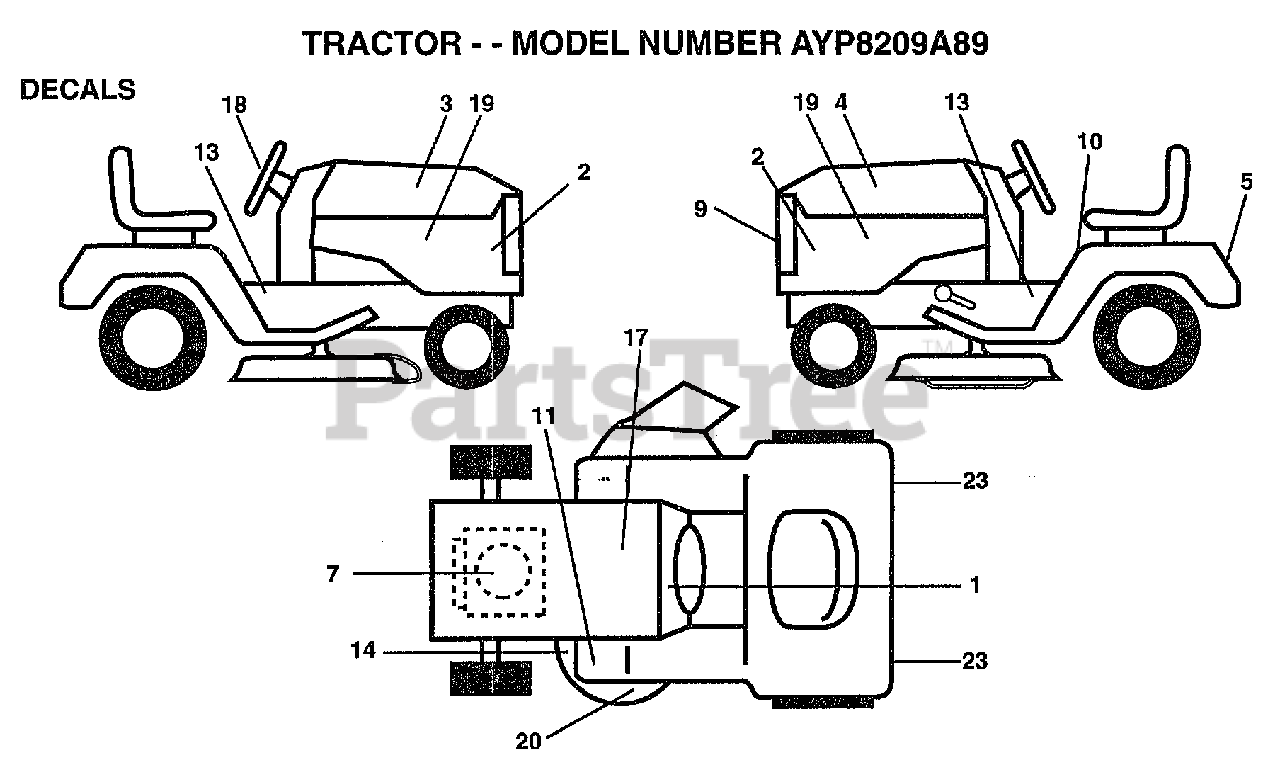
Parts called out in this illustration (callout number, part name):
1	"DECAL-OPER,GEAR D"
2	NAMEPLATE.HD.WIZA
3	DECAL.HD.RH.WIZRD
4	DECAL.HD.LH.WIZRD
6	DECAL.GRILLE.WIZ+
7	DECAL, ENGINE
9	DECAL.GRILLE.WIZ+
10	"DECAL DANGER,FEND"
13	"DCL.CHASSIS.50"""
17	DECAL.BATRY.3-3908
18	DECAL INS STG WHL
19	DECAL.PANEL.SIDE
20	DECAL DECK WIZ +
23	REFLECTOR-TAIL YT
